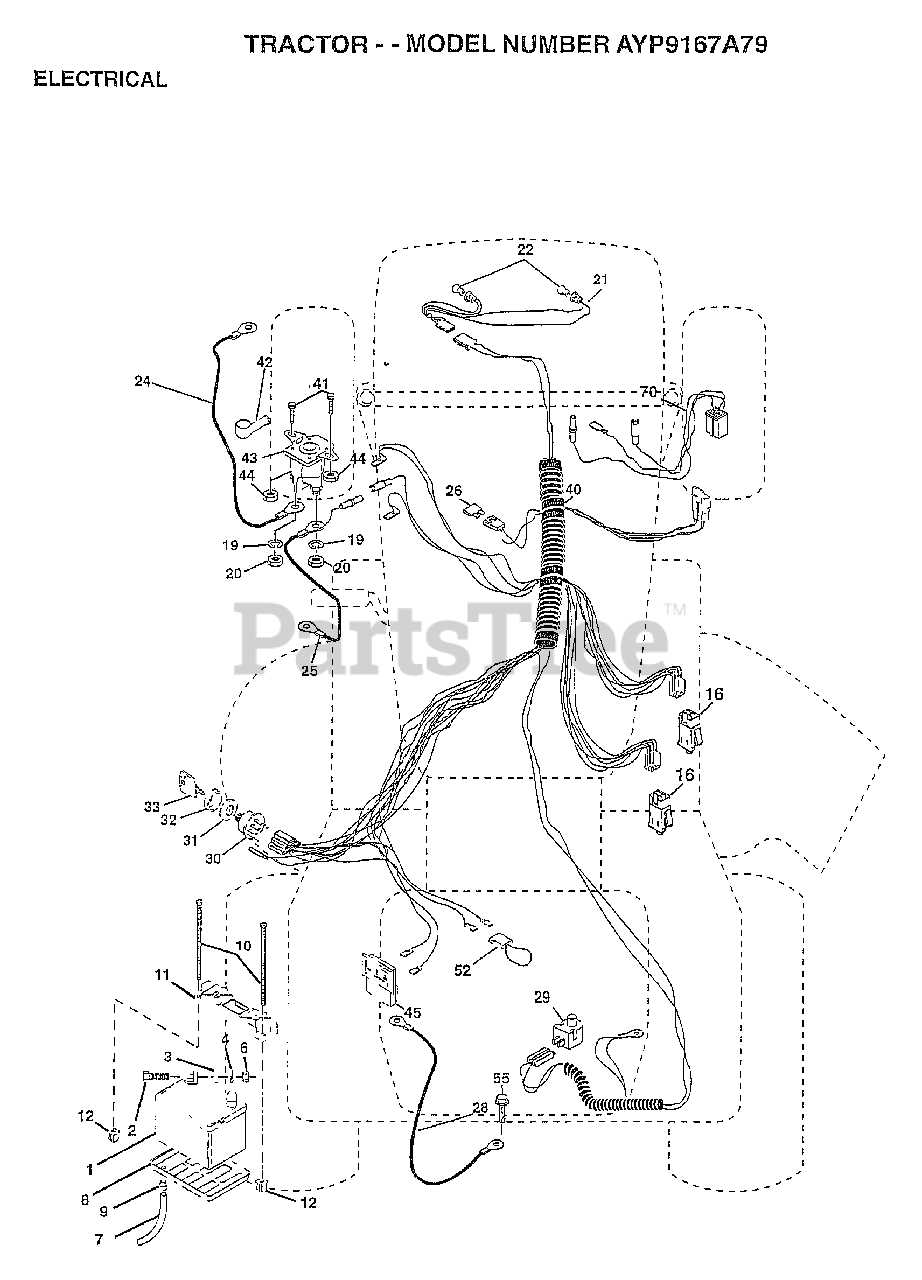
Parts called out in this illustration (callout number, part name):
2	BOLT LT
3	WASHER
4	LOCKWASHER
7	"DRAIN TU T, BATT"
8	"TRAY T, BATTERY"
9	HOSE CLAMP T
11	HOLDDOWN BATTERY
16	SWITCH INTERLOCK
20	NUT
21	"HARNESS,LIGHT SOC"
22	HEADLAMP BULB
24	"CABLE T, BATTERY"
25	CABLE.6GA.22W/16W
26	FUSE HYT
28	CABLE.GRND.6GA.21
29	SWITCH SEAT
30	SWITCH IGN 4POS
31	NUT IGNITION
32	COVER KEY SWITCH
33	KEY
40	HARNESS-IGNITION
41	BOLT HXHD FIN
44	NUT HXKEP 1/4X20
45	AMMETER
52	PROTECTION LOOP
55	SCREW LT
70	HARNESS ENGINE
